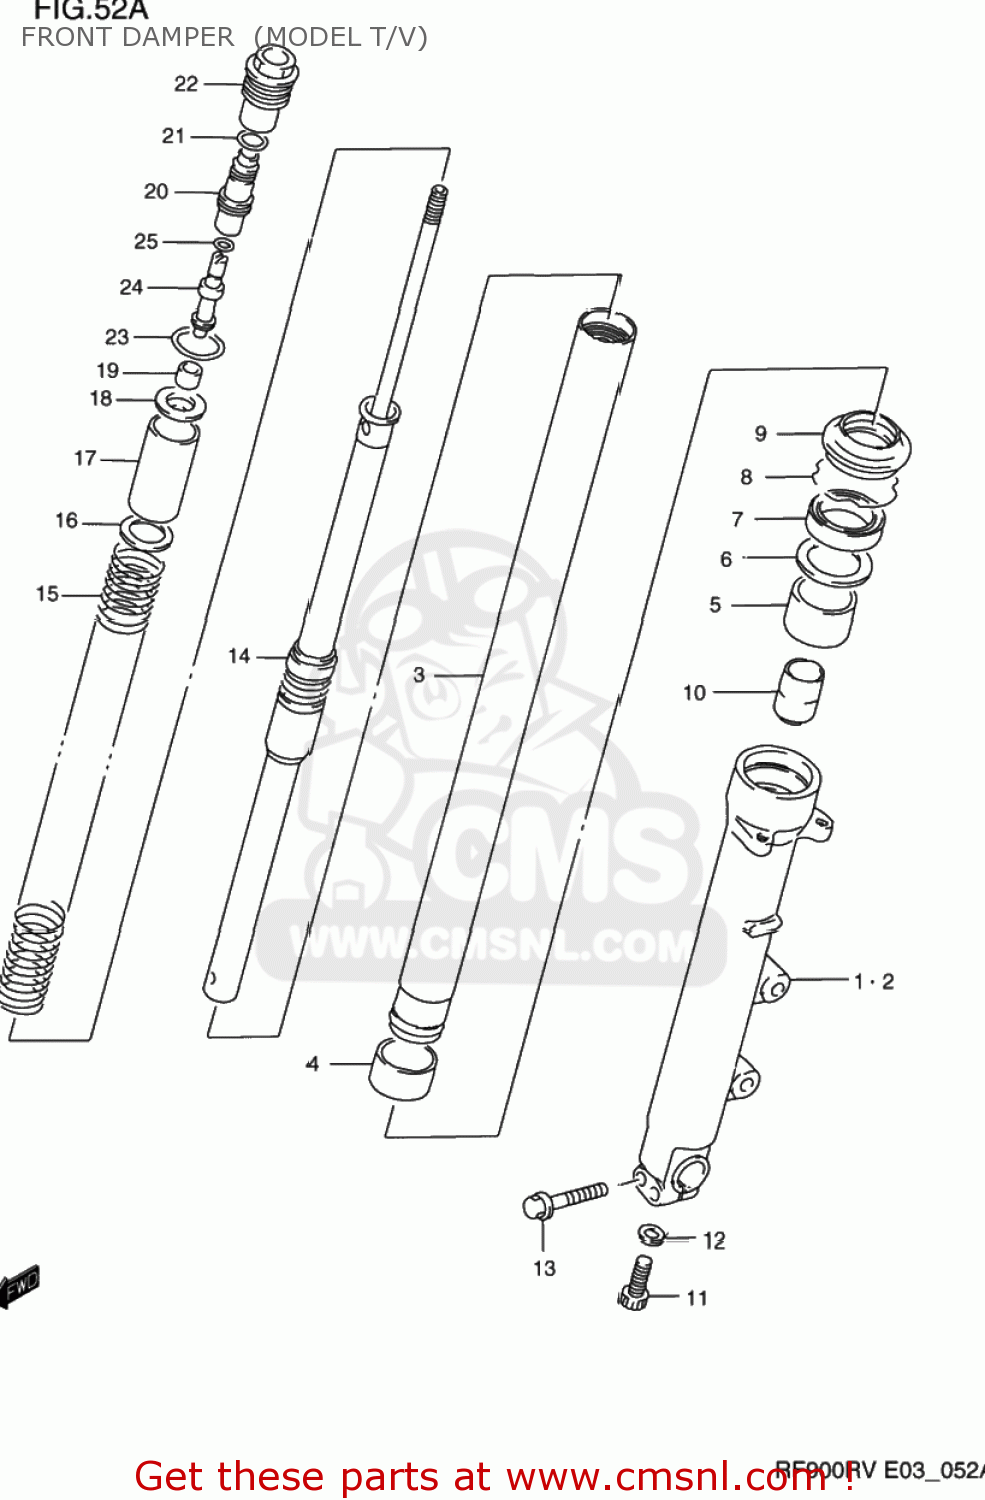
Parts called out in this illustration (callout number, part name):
1	TUBE,OUTER,R
2	TUBE,OUTER,L
3	TUBE,INNER
4	BUSH,SLIDE
5	BUSH,GUIDE
6	SPACER,SEAL
7	SEAL,OIL
8	CIRCLIP,FORK OIL SEAL
9	SEAL,DUST
10	PIECE,OIL LOCK
11	BOLT(8X27)
12	GASKET (NAS)
13	BOLT
14	DAMPER,FR
15	SPRING,MAIN
16	SEAT,SPRING LWR
17	COLLAR,SPRING(35X37X50)
18	SEAT,SPRING UPR
19	NUT
20	ADJUSTER,SPRING
21	O RING(D:2.5,ID:13.8)
22	BOLT,FORK
23	O RING
24	PIECE,ADJUSTER
25	O RING(D:1.9,ID:3.8)
